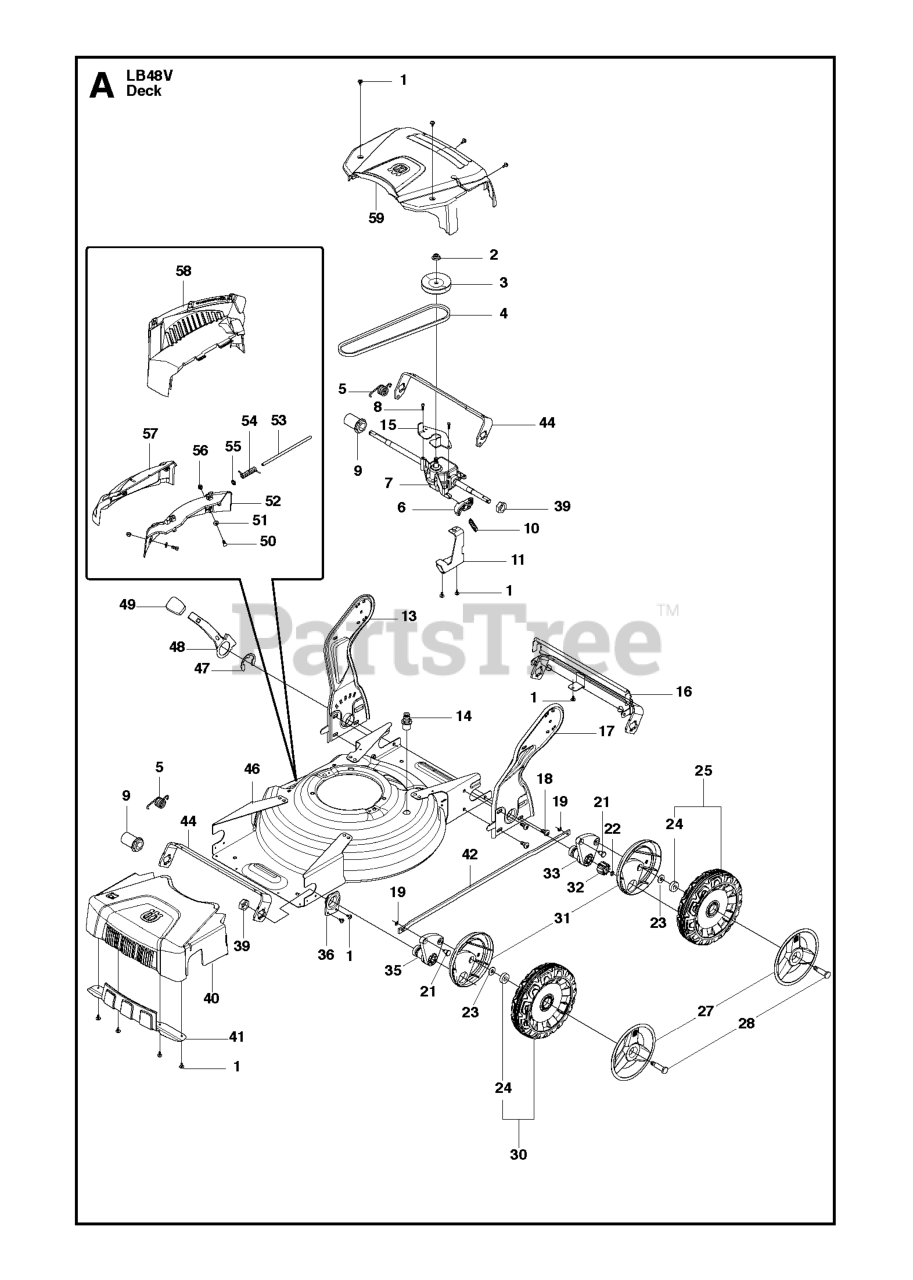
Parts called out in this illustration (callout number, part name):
1	SCREW ITXPANTT M5X10 ZPB (A00
4	BELT WRAPPED V-BELT Z 29.5
8	SCREW ITXPANT T50X16 ZN/FE (A
19	FASTENER
24	BALL BEARING
46	CHASSIS 48S A009 PAINTED
59	REAR COVER A009-2
